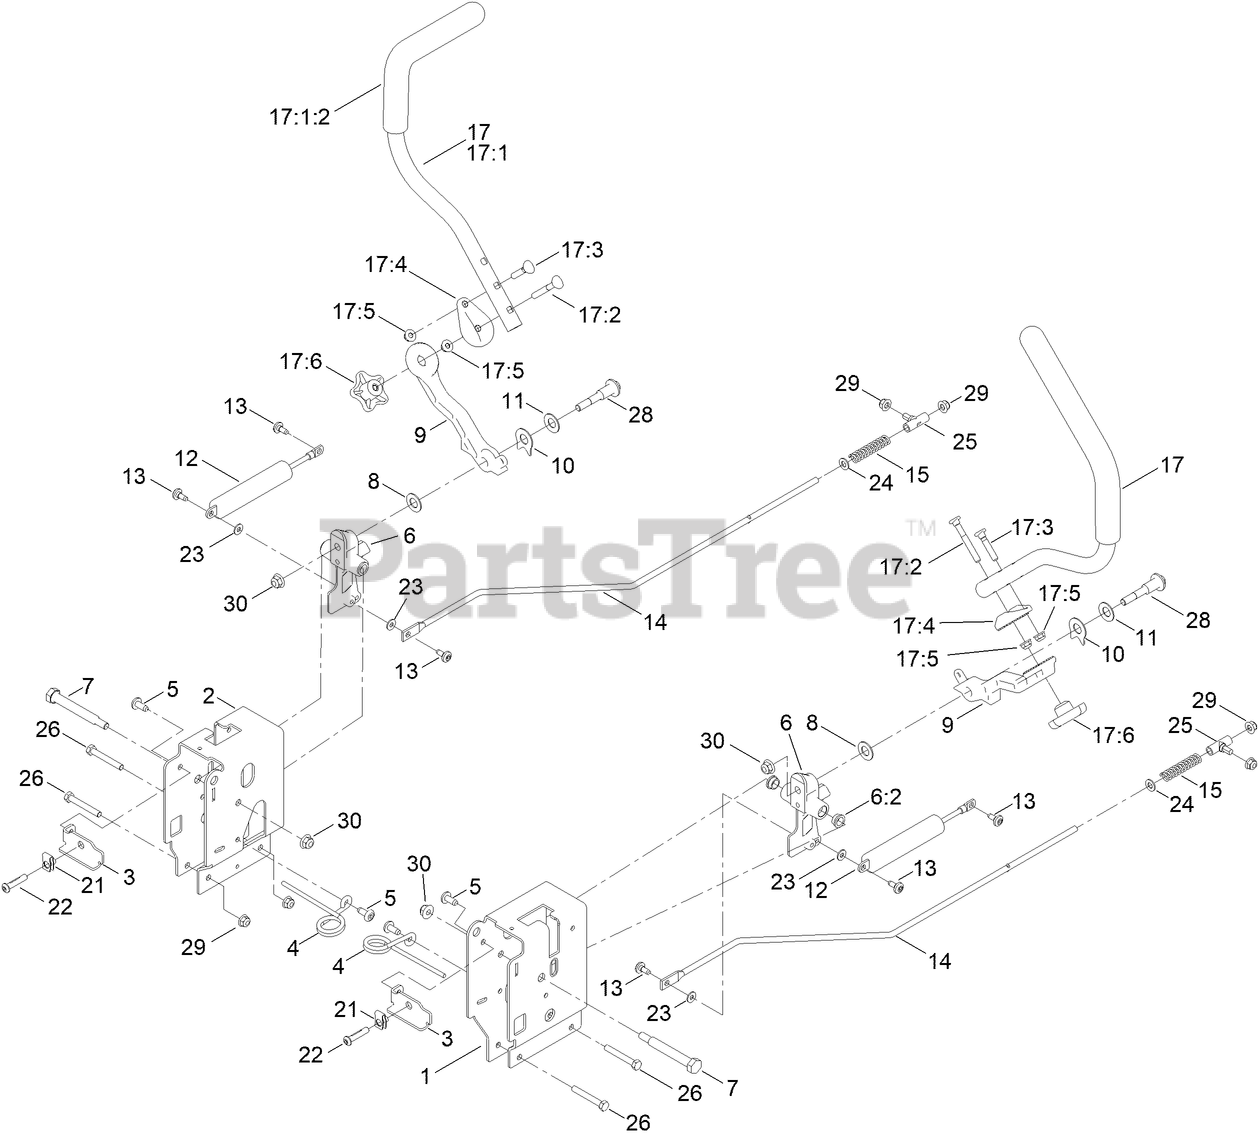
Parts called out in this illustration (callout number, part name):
1	CONTROL BOX - LH G7
2	CONTROL BOX - RH G7
3	ADJUSTMENT PLATE-CONTROL BOX
4	SPRING-TORSION
6	PIVOT ARM ASM
6:2	BUSHING-FLANGE
7	BOLT-PIVOT
8	WASHER-NYLON
9	ARM-CONTROL, 32 TEETH
10	SPACER, ANTI-ROTATION
11	WASHER-BELLEVILLE
12	DAMPER - NON CAVITATING
13	SCREW-SHOULDER
14	ROD - HYDRO, LH
15	SPRING-COMPRESSION
17	HANDLE-CONTROL, ASM
17:1	HANDLE-CONTROL,
17:2	SCREW-HANDLE
17:3	SCREW-HANDLE
17:4	DISC-ADJUSTMENT HANDLE, 32 TEETH
17:5	NUT-HF
17:6	KNOB-HANDLE
22	SCREW-HSBH
23	WASHER
24	WASHER-PLAIN
25	MOUNT-ROD, HYDRO
26	SCREW-HH
28	BOLT-PIVOT
29	NUT-HF, NI
30	NUT-HF, NI
